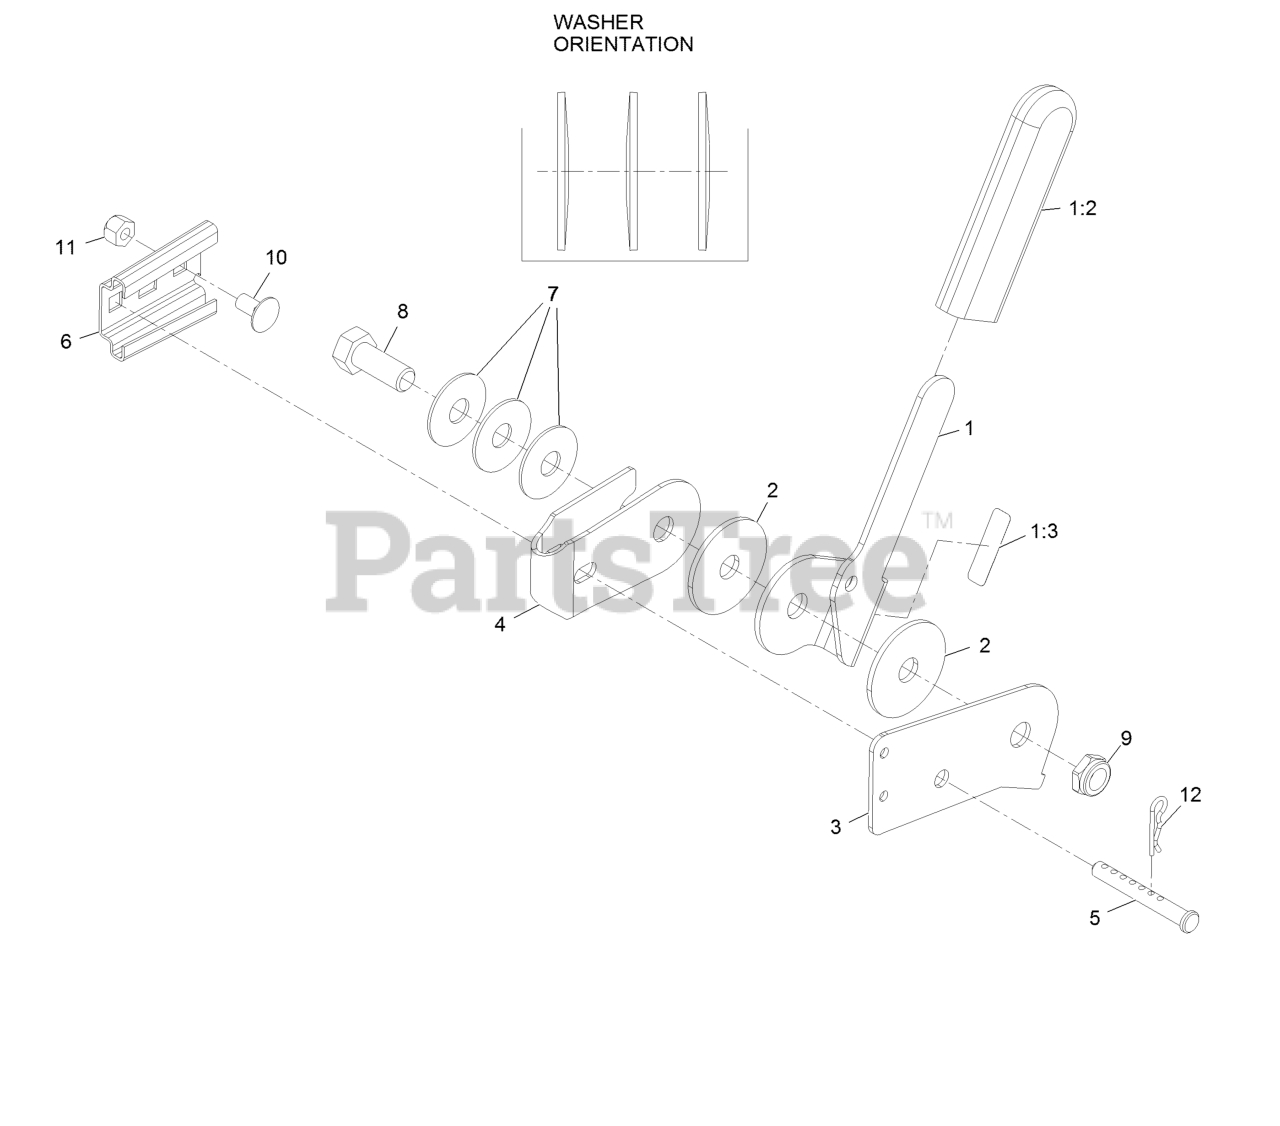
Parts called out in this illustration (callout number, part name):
1	Control Handle ASM-Ocd
1:2	Grip-Lever
1:3	Decal-Operation
2	Disc-Friction
3	Bracket,Control Mount
4	Bracket,Handle Mount
5	Pin-Clevis
6	Bracket-Mounting,Smv
7	Washer-Spring Disc
8	Screw-HH 1/2-13 X 1 1/4
9	Nut-Nyloc 1/2-13 Thin
10	Bolt-Carriage 5/16-18 X 5/8
11	Nut-Nyloc 5/16-18
12	Hairpin-Cotter
